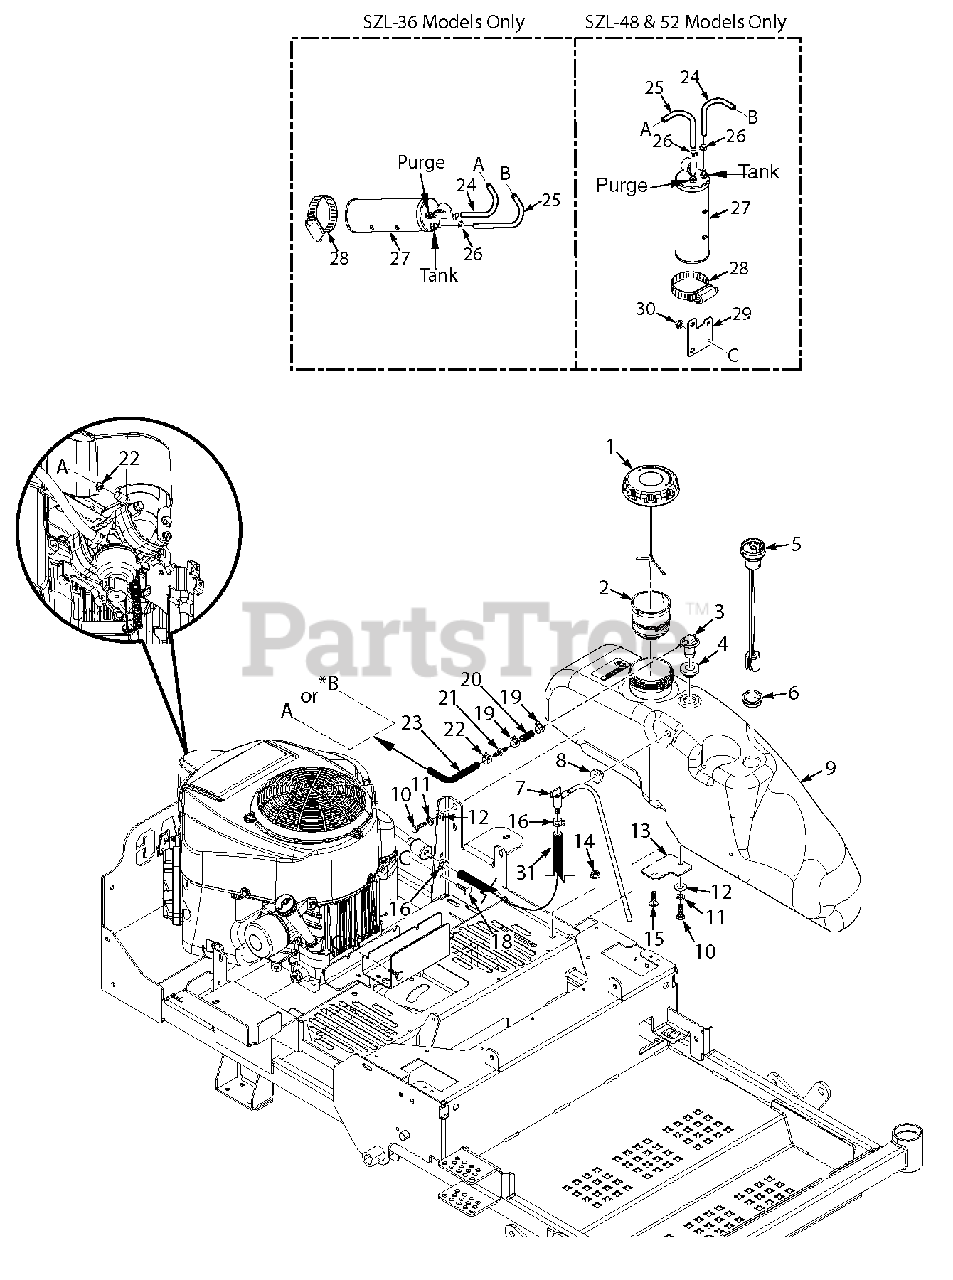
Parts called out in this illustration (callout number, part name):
1	Fuel Cap
1	Fuel Cap, C.A.R.B.
2	Fuel Neck Insert
3	Remote Vent, No Valve
4	Grommet, Kelch
5	Fuel Gauge (requires #6)
6	Grommet, Fuel Gauge
7	Valve, Fuel Shut Off
8	Bushing, .56 Dia. Viton
9	Fuel Tank Assembly SZL 48 & 52
9	Fuel Tank Assembly SZL-36
10	Bolt, Hex Head 5/16-18 x 3/4"
11	Lockwasher, 5/16"
12	Flatwasher, 5/16-.375 x .875 x .083
13	Mounting Bracket, Fuel Tanks Front
14	Nut, 5/16-18 Serrated Flange
15	Bolt, Carriage 5/16-18 x 1"
16	Clamp, Fuel Hose 1/4"
17	Hose, Non-perm Fuel - 1/4" Dia. (order by inch)
18	Bolt, Carriage 1/4-20 x 3/4"
19	Clamp, Fuel Hose 7/32" ID
20	Hose, 1/4" Vapor Return (order by inch)
21	Mender, 1/4 x 3/16 w/.02 Hole
22	Clamp, Vapor Hose -3/16"
23	Hose, Vapor (order by inch)
24	Hose, Vapor (order by inch)
25	Hose, Vapor (order by inch)
26	Clamp, Vapor Hose - 3/16"
27	Carbon Cannister, 400cc
28	Clamp, 3-1/2" Max. Dia.
29	Bracket, Cannister Mount
30	Nut, 1/4-20 Serrated Flange
31	Hose, 1/4 fuel line x 17.00
